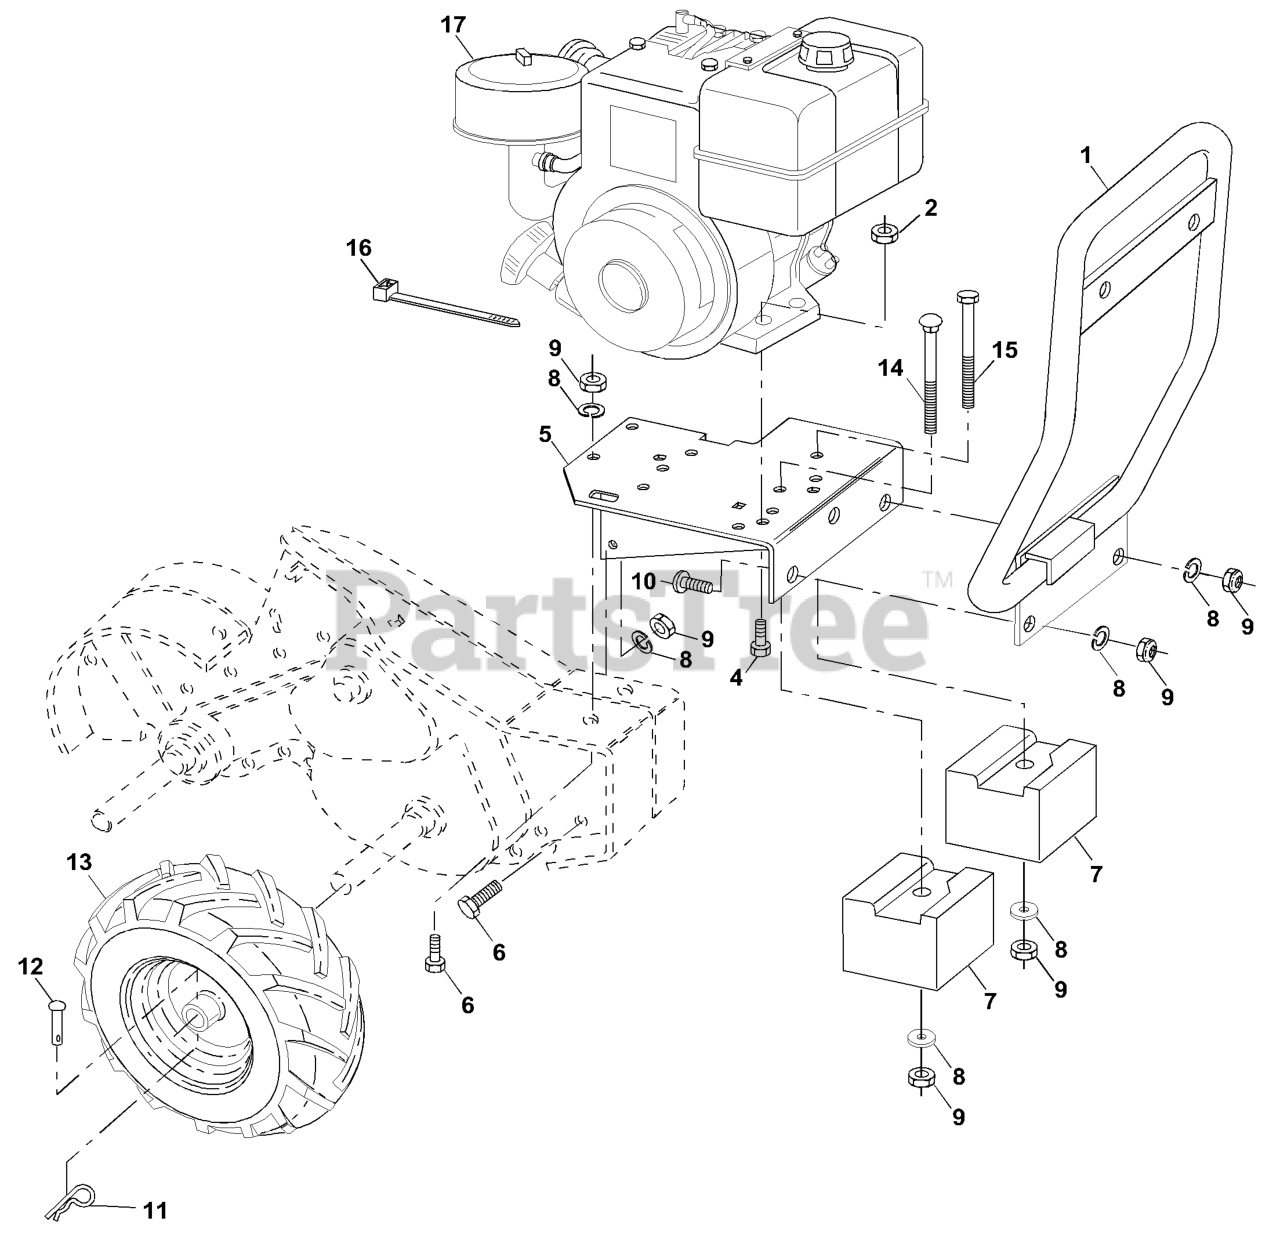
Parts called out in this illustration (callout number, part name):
2	NUT
4	BOLT, HEX 5/16-18X1-3/4
5	ENGINE BRACKET
6	BOLT
7	COUNTER WEIGHT RH
8	WASHER, LOCK 3/8
9	NUT.HEX.3/8-16UNC
10	BOLT D
11	SPRING TI
13	TIRE.16X4-8.CHEVRON.TILLER
13	RIM
13	VALVE STEM LT
14	Bolt, Carriage 3/8-16 x 4-1/2
15	BOLT, HEX 3/8-16X4-1/2
16	TIE CABLE CRT
